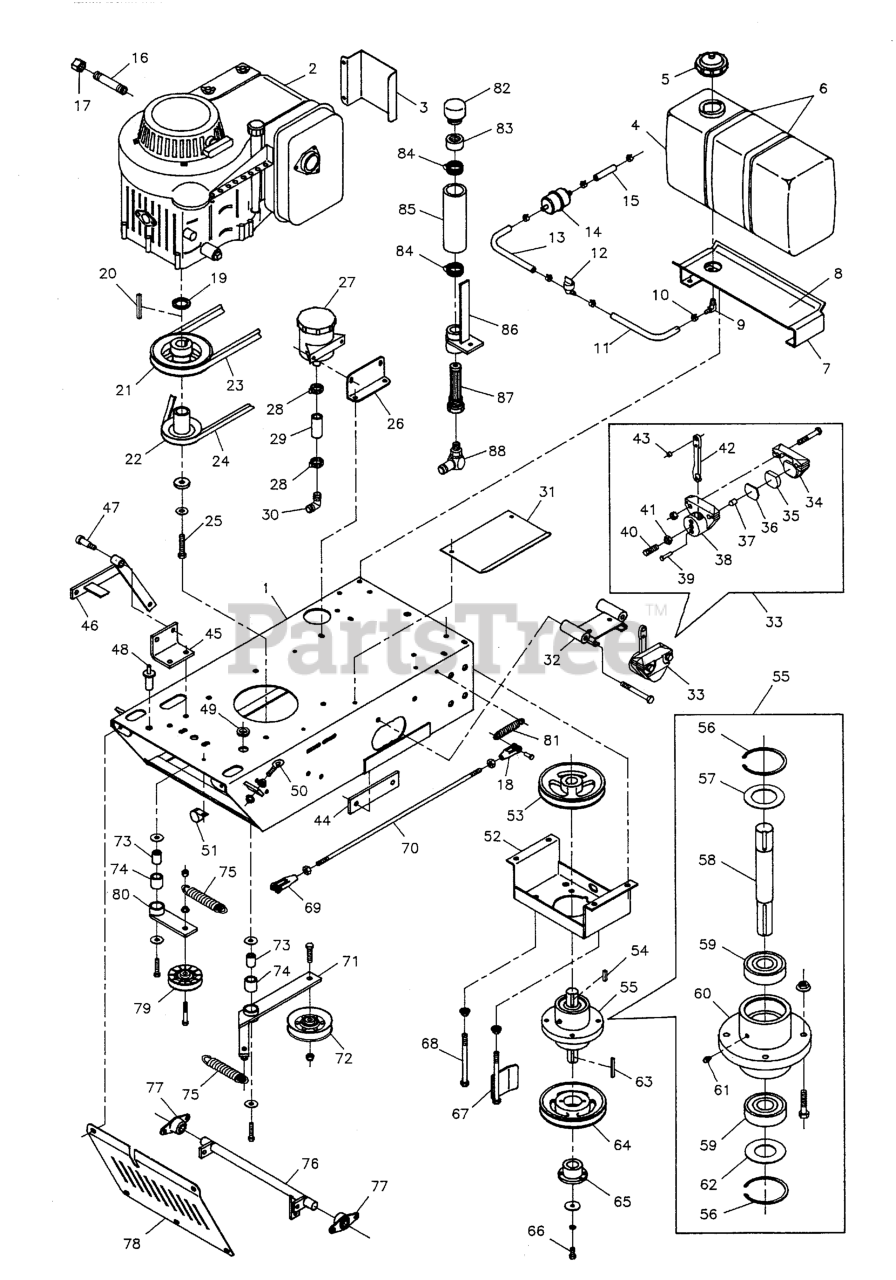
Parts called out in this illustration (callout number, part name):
1	Engine Deck
1	Engine Deck 32"
3	Muffler Guard (Kohler)
3	Muffler Heat Shield
4	Gas Tank
5	Gas Cap
6	Gas Tank Strap
7	Gas Tank Mount
8	Gas Tank Safety Walk
9	90 Degree Brass Fitting
10	CLAMP, Hose
11	1/4" Fuel Line, 8" Long
11	HOSE, 1/4" FUEL, 9.00"
12	VALVE, Fuel Shut-Off
13	1/4" Fuel Line, 14" Long
13	1/4" Fuel Line, 22" Long
14	FUEL FILTER
15	1/4" Fuel Line, 5" Long
16	Pipe Nipple
17	CAP, 3/8 NPT
18	CLEVIS, 5/16-24, Steel
19	SPACER, 1.13 x 1.50 x .19
20	KEY, 1/4 SQ. X 2-1/2
21	ENGINE PULLEY
22	PULLEY, Transmission Drive
23	Belt, Jackshaft Drive
24	Belt, Transmission Drive
25	BOLT, M10 x 50MM
26	Oil Reservoir Mount
27	RESERVOIR, Hydraulic
28	CLAMP, #10 Hose
29	Hose, 2"
30	FITTING, 5/8", 90 Deg.
31	HEAT SHIELD
32	BRAKE CALIPER MOUNT
33	BRAKE CALIPER ASSEMBLY, RH, Complete
33	BRAKE CALIPER ASSEMBLY, LH, Complete
35	BRAKE PAD
36	BACK PLATE
37	ACTUATOR PIN
38	Brake Housing
39	GROOVE PIN
40	ADJUSTER BOLT
41	JAM NUT
43	SPACER, .25 x .37 x .25
44	Brake Brace
45	PIVOT MOUNT
45	Clutch Pivot
46	BLADE ENGAGEMENT PIVOT
46	Blade Pivot
47	SHOULDER BOLT, 1/2 x 1
47	Actuator Spacer
48	SWITCH, Plunger, NO
48	Safety Switch
49	GROMMET, 1/2"
50	EYEBOLT, 5/16-18 x 2-1/8
51	Saftey Interlock
51	Interlock
52	Jack Shaft Mount
53	SPINDLE PULLEY
54	KEY, 1/4 SQ. X 1
55	JACKSHAFT SPINDLE ASSEMBLY, Complete
56	SNAP RING, Internal
57	SPINDLE WASHER, Top
58	SHAFT, Spindle
59	BEARING
60	SPINDLE HOUSING
61	GREASE FITTING
62	SPINDLE WASHER, Bottom
63	KEY, 3/16 SQ. X 1-1/4
64	PULLEY, Spindle
65	BUSHING, Tapered Hub
66	BOLT, 5/16-24 x 3/4
67	BELT GUIDE
68	BOLT, 3/8-16 x 5
69	CLEVIS, 5/16-24, Plastic
70	ROD, Linkage
71	IDLER ARM ASSEMBLY
72	IDLER PULLEY
73	SPACER, .32 x .75 x 1.06
74	BUSHING, Brass
75	SPRING, Extension
76	ROD, Transmission Control
77	BEARING, Flange
79	IDLER PULLEY
80	IDLER ARM ASSEMBLY
81	SPRING, Extension
82	BREATHER, FILTER
83	Reservoir Cap
84	CLAMP, #24 Hose
85	Reservoir Tube
86	Reservoir Mount
87	STRAINER
88	FITTING, 1/2" NPT, 90 Deg.
